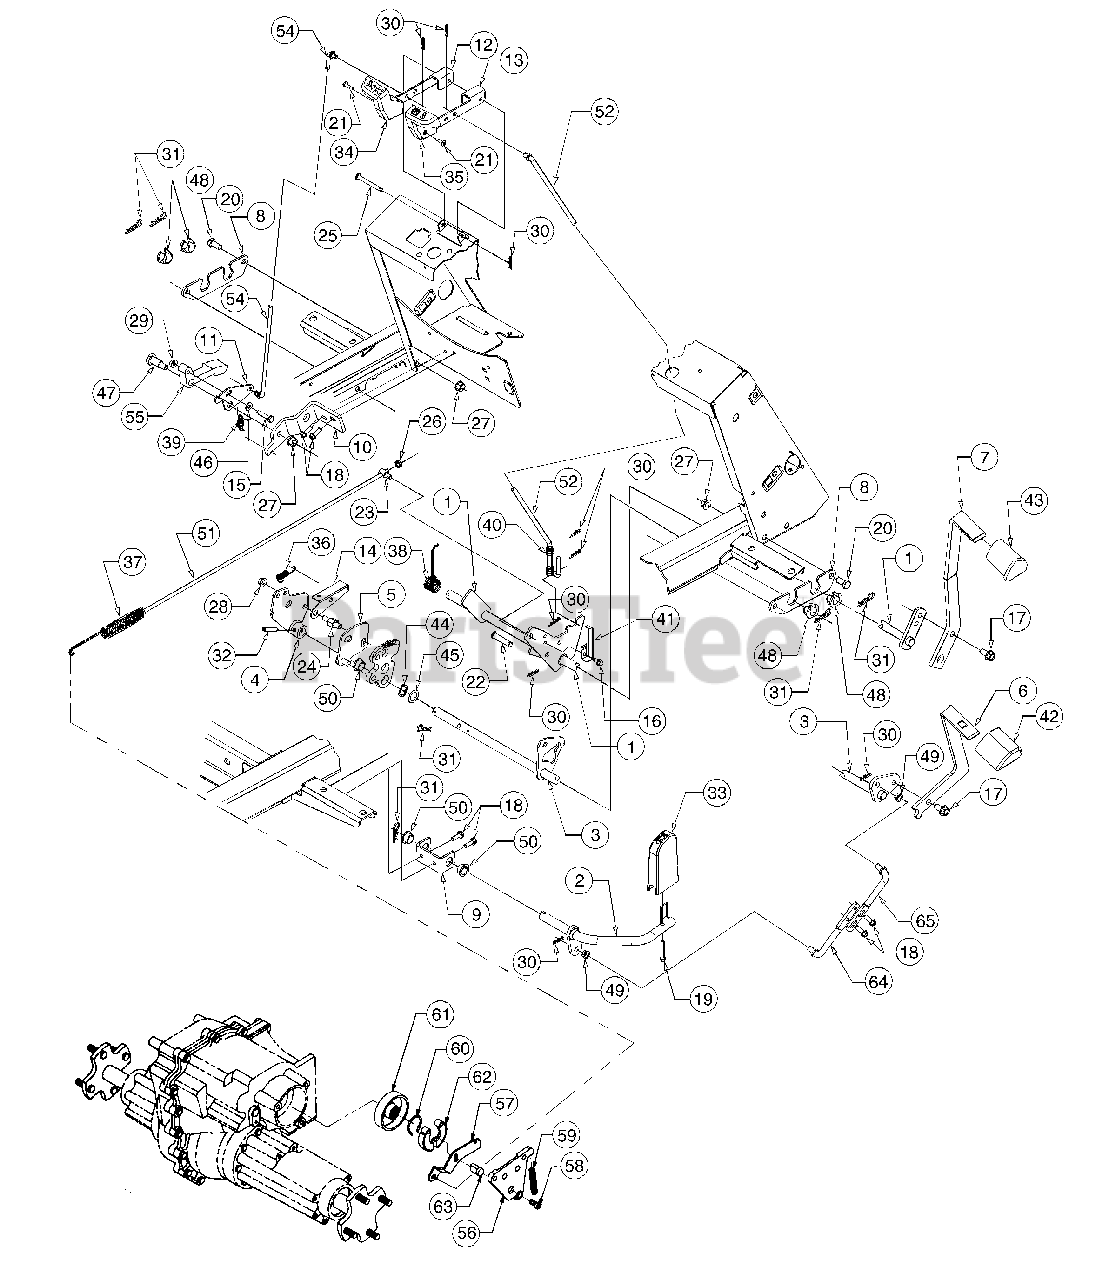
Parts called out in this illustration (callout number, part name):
1	Shaft Assy, Brake
4	Cam Assy, Control
5	Plate Assy, Disengagement
6	Pedal, Forward
7	Pedal, Brake
8	Plate, Bearing Mounting
10	Bracket, Cruise
11	Plate, Rod Adjustment
15	Screw, Hex Cap, 1/4-20 x 1.25
16	Screw, Hex Wshr Tap 1/4-20x.5
17	Screw, Hex Wshr Tap 3/8-16x.75
18	Screw, Hex Wshr Tap 1/4-20x.75
19	Screw, Truss Mach, #12 x 1.5
20	Screw, Hex Cap, 3/8-16x.75 GR5
21	Screw, Phil Hd Pan, #10-24 x .75
22	Pin, Clevis, 3/8 x 1.62
23	Ferrule, Adjustment, 1/4-20 Thrd
24	Stud, Actuator
25	Pin, Clevis, .25 x 2.38 Lg
26	Nut, Hex Sems, 1/4-20
27	Nut, Hex Flange Lock, 3/8-16
28	Nut, Hex Flange Lock, 5/16-18
29	Nut, Hex Flange Lock, 1/4-20
30	Pin, Int Cotter, 5/16 Dia x 1.12 Lg
31	Pin, Int Cotter, 3/8 Dia x 1.62
32	Pin, Spiral Spring, 1/4 x 1.5
33	Pedal, Reverse
34	Knob, Cruise
35	Knob, Brake Lock
36	Spring, Extension, .38 OD x 2.1
37	Spring, Extension
38	Spring, Torsion
39	Spring, Ext, .437 OD x 1.32
40	Spring, Compression, .50 x 2.23
41	Spring, Switch Actuator
42	Pad, Forward Foot Control
43	Pad, Brake Foot
44	Washer, Wave, .625 x .885 x .015
45	Washer, Flat, .635 x 1.0 x .020
46	Washer, Flat, 1/4 x .63 x .051
47	Shoulder Bolt, .50 OD x .840
48	Bearing, Hex Flange Split
49	Bearing, Flange, .375 x .58 x .25
50	Bearing, Flange, .626 x .93 x .344
51	Rod, Brake
52	Rod, Parking Brake
54	Rod, Cruise
55	Latch, Cruise
56	Plate, Brake
57	Arm, Brake
58	Screw, Low Hd Cap, 3/8-16 x .75
59	Spring, Compression
60	Spring, Brake
61	Drum, Brake
62	Shoe, Brake
63	Actuator, Brake Shoe
64	Rod, Rear Connecting
65	Rod, Front Connecting
